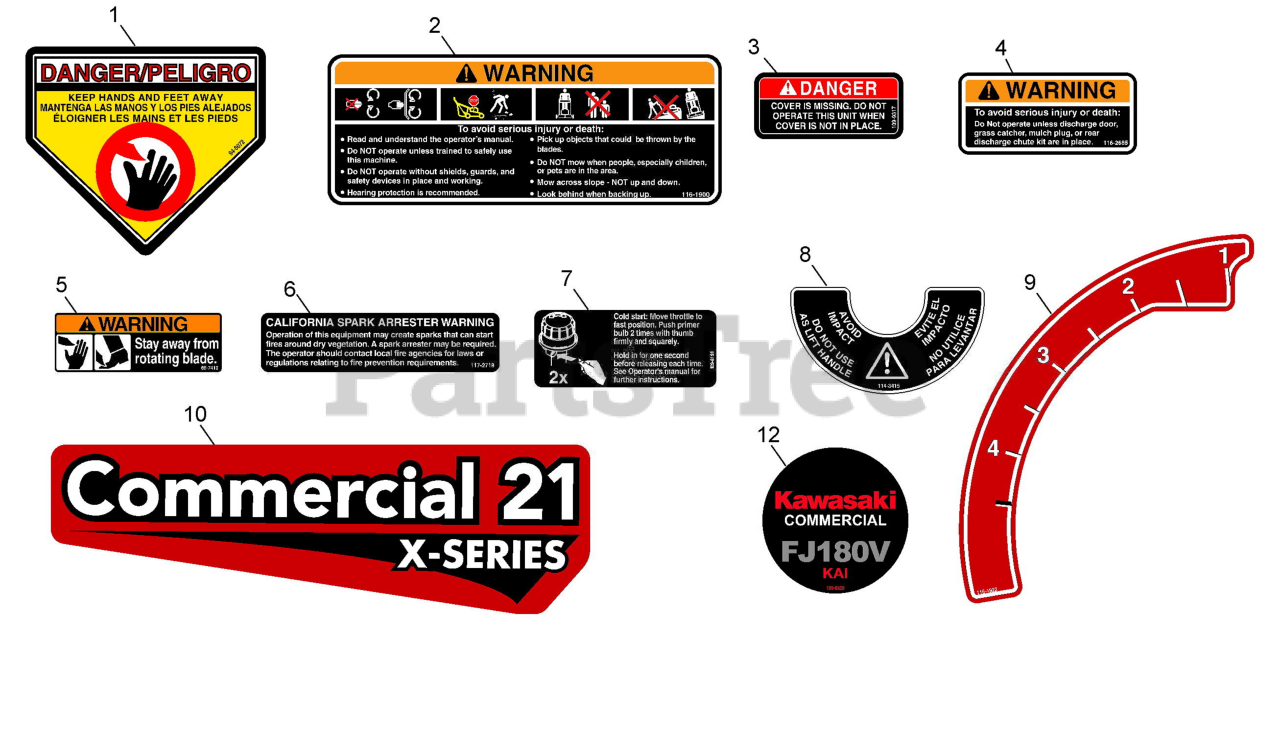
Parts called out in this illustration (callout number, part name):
1	DECAL-DANGER
2	DECAL-WARNING
3	DECAL-COVER MISSING
4	DECAL-WARNING DOOR SM
5	DECAL-BLADE
6	DECAL-ARRESTER, SPARK
7	DECAL, PRIMER
9	DECAL-HEIGHT OF CUT
10	DECAL-COMM 21 X-SERIES
